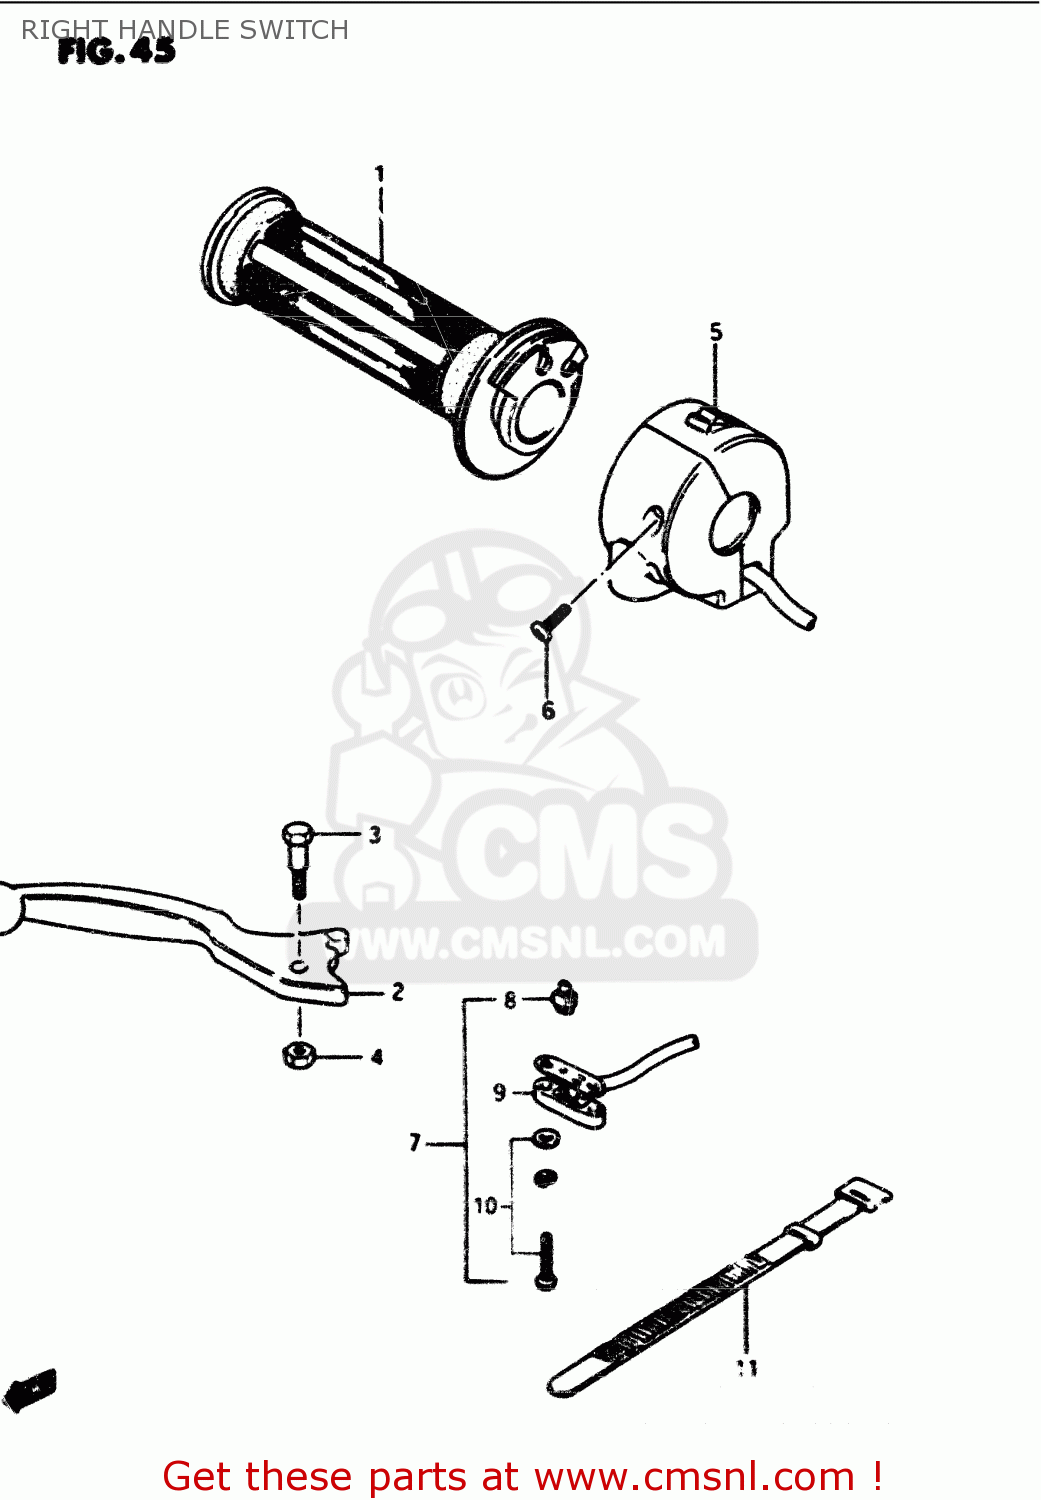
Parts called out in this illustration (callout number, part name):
1	GRIP,THROTTLE
2	LEVER,BRAKE
3	BOLT,LEVER PIVOT
4	NUT
5	SWITCH ASSY, HANDLE RH (FLAT)
6	SCREW
7	SWITCH ASSY,STOP
8	CONTACT,SWITCH
9	COVER,FR BK TERMINAL BASE
10	SCREW
11	CLAMP(L:120)
